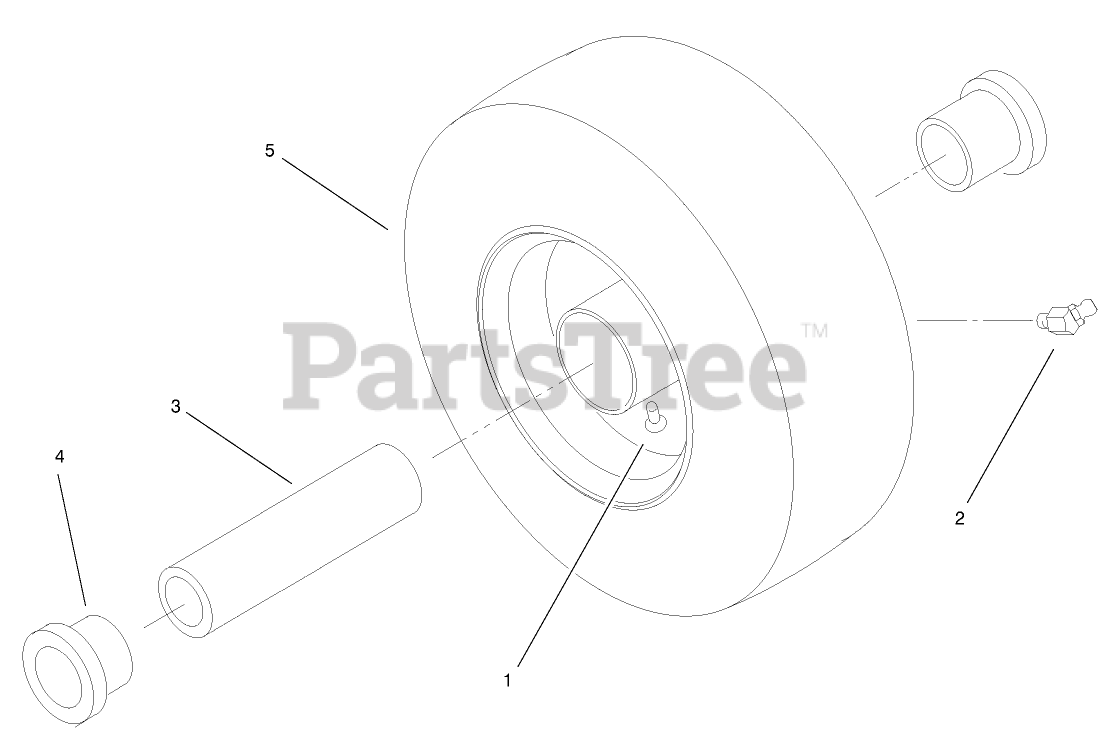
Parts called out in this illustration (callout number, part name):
1	STEM-VALVE
2	FITTING-LUBE, 45 DEG
3	BEARING
4	BEARING-OUTSIDE
5	TIRE-TUBELESS
